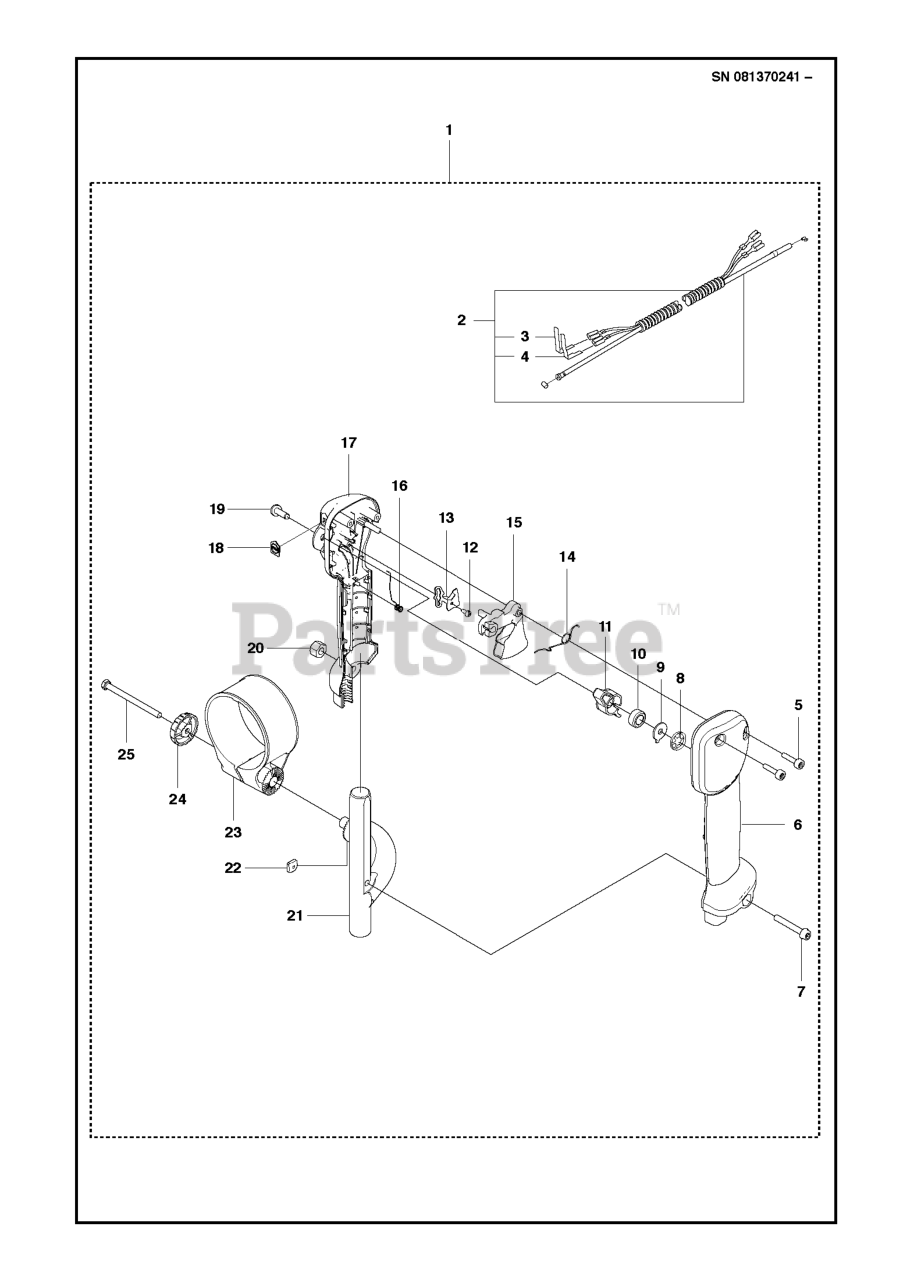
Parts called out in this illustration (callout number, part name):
1	HANDLE ASSY
2	WIRING ASSY
3	CONTACT SPRING
4	CONTACT SPRING
5	SCREW
6	HANDLE HALF (R)
10	SPRING RUBBER
11	LEVER STOP
15	TRIGGER 848L5W34C0
17	HANDLE HALF (L)
19	SHAFT PIVOT
21	HOLDER, HANDLE
